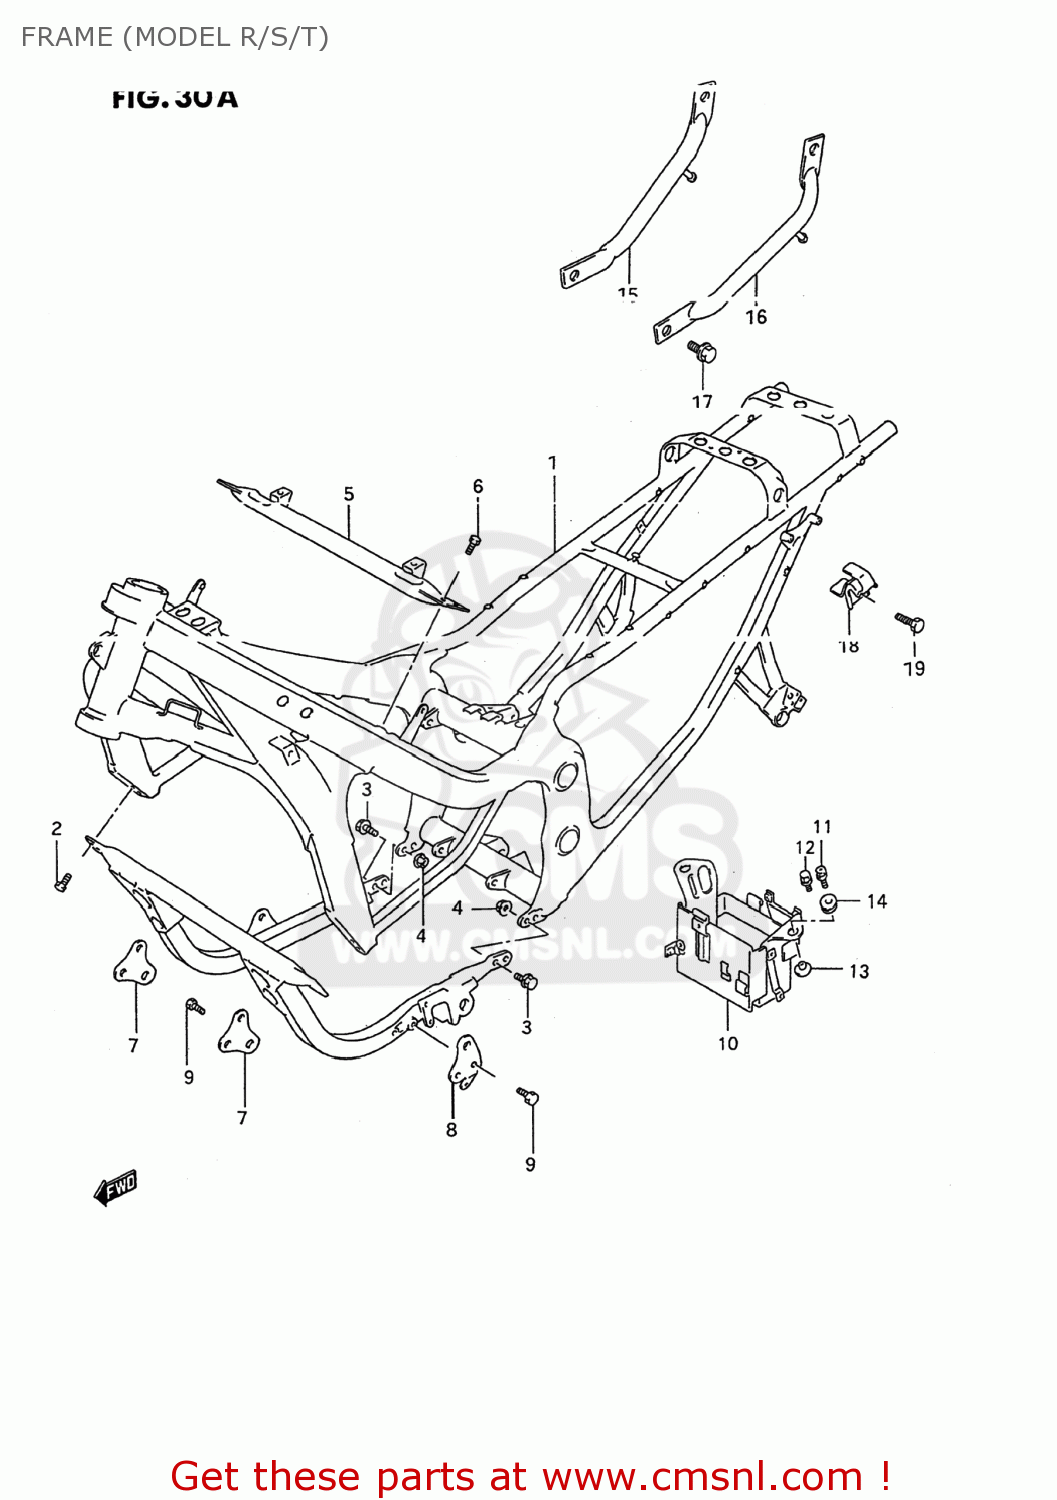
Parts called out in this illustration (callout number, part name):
1	FRAME SET(BLACK)
2	BOLT
3	BOLT
4	NUT
5	TUBE,FRAME BRIDGE NO.2
6	BOLT(8X20)
7	PLATE,ENG MTG NO.1
8	PLATE,ENG MTG NO.2,L
9	BOLT, UPPER
10	HOLDER,BATTERY
11	BOLT L:30
12	BOLT
13	SPACER COMP,BATTERY
14	CUSHION
15	GRIP,REAR,RIGHT
16	GRIP,RR,L
17	BOLT
18	HOLDER,HELMET
19	BOLT
